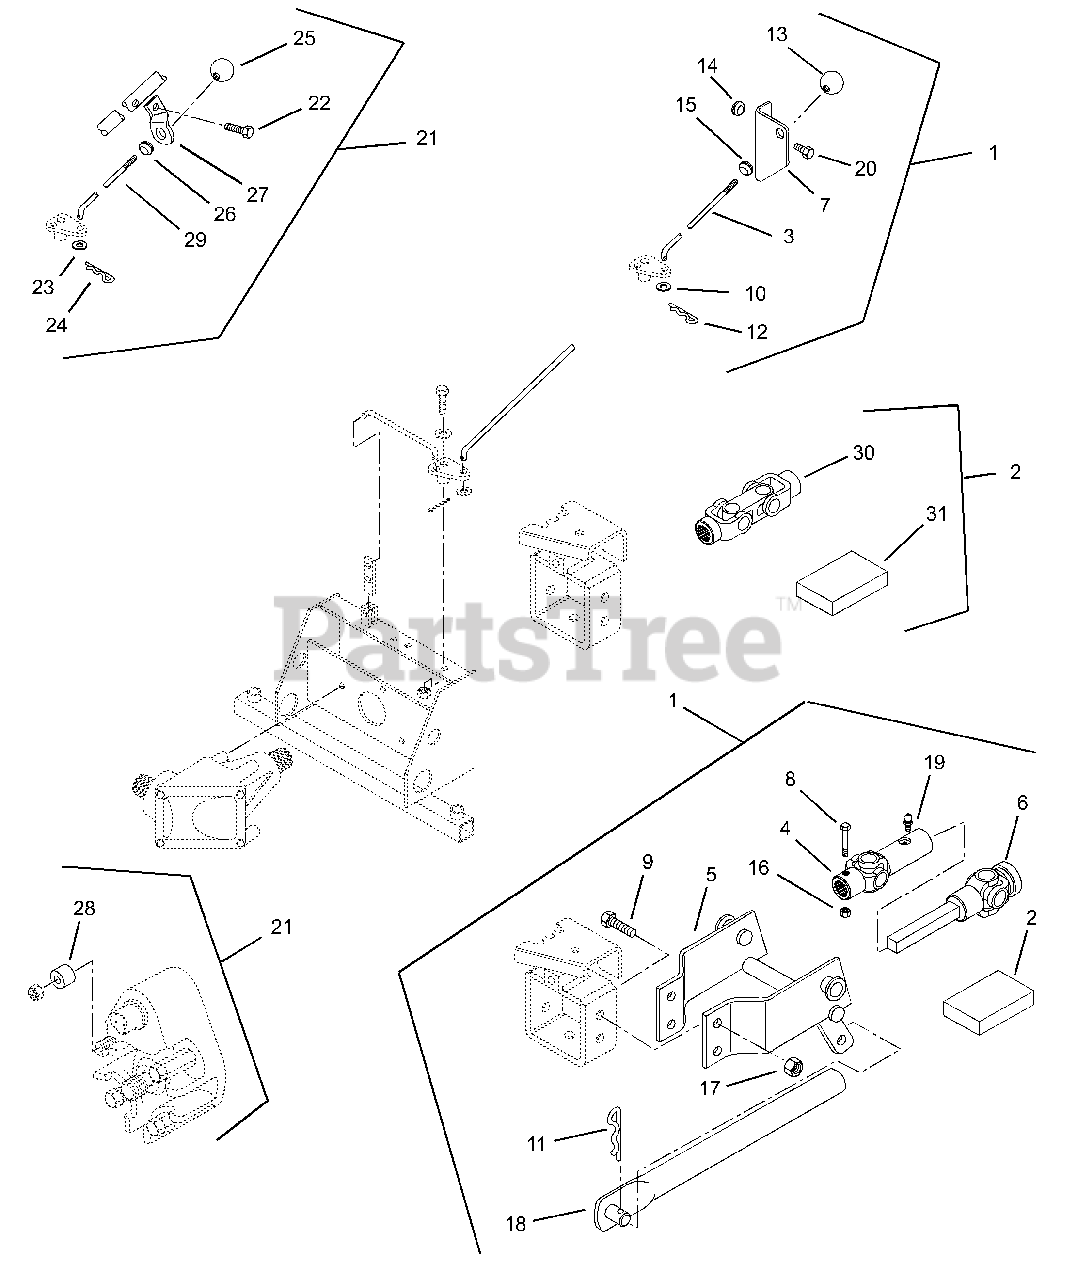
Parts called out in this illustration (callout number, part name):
1	Kit, Power Brush for 4-Wheel Tractor
2	Kit, Universal Joint Repair
3	Rod, Control
4	Universal Joint-Female End
5	Weldment, Adapter
6	Universal Joint-Male
7	Bracket
8	Bolt-Hex .25-20 x 2.00 Grade 5
9	Bolt-Hex .50-13 x 1.50 Grade 5
10	Washer-Flat-Steel .281 x .62 x 065
11	Pin-Hair-External .15 x .937
12	Hair Pin Cotter .08 x .18 x 1.18
13	Knob
14	Grommet, Plastic
15	Grommet, Shifter
16	Nut-Locking-Nylon .25-20
17	Nut-Locking-Nylon .50-13
18	Rod, Push Weldment
19	Fitting-Lube .25-28
20	Screw-Self Tapping .25-20 x .75 Hex Washer Head
21	Kit, Power Brush for 2-Wheel Tractor
22	Bolt-Hex .50-13 x 2.75 Grade 5
23	Washer-Flat-Steel .281 x .62 x .065
24	Hair Pin Cotter .08 x .18 x 1.18
25	Knob
26	Grommet, Shifter
27	Guide, Control Rod
28	Bushing Sleeve .531 x .991 x .600
29	Arm, Control
30	Assembly, Double Universal Joint
31	Journal Cross and Bearing Assembly
